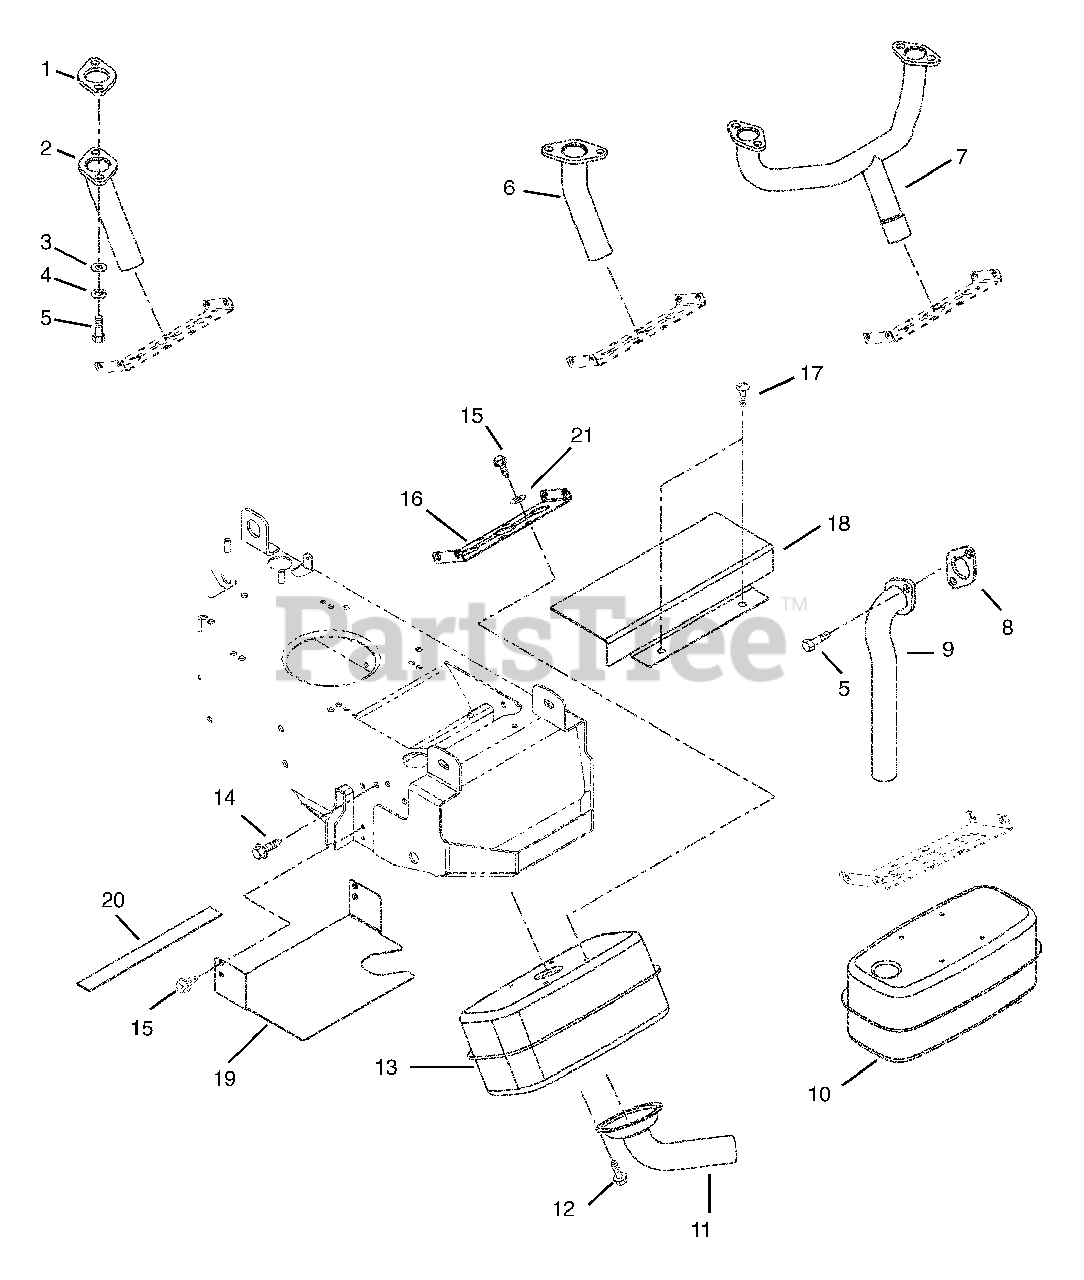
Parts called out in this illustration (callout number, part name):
1	GASKET- 12.5/13 TEC (#35-414)
2	TUBE - EXHAUST WELD. 13 HP
3	WSHR-FL-STL .323X.625X.062 YWZ
4	@WSHR-LK .31X.078 REG YWZC
5	SCR-CAP .31-18X.75 S/HD
6	PIPE - EXHAUST
7	PIPE - EXHAUST TWIN B&S
8	GASKET B&S#272293
9	PIPE - EXHAUST
10	MUFFLER W/DEFLECTOR
11	DEFLECTOR - EXHAUST
12	SCR-TAP 8-32X.38 SL HWH YWZC
13	MUFFLER - EXHAUST
14	@SCR-TAP .31-18X.50 HWH TR YWZ
15	@SCR-TAP 12-24X.75 HWH YWZC
16	BRACKET - MUFFLER
17	@SCR-TAP .31-18X.50 HWH TR YWZ
18	SHIELD - HEAT
19	SHIELD - HEAT
20	HEAT SHIELD- FABRIC 1X10.75
21	@WSHR-FL-STL.250X.56X.049 YWZC
